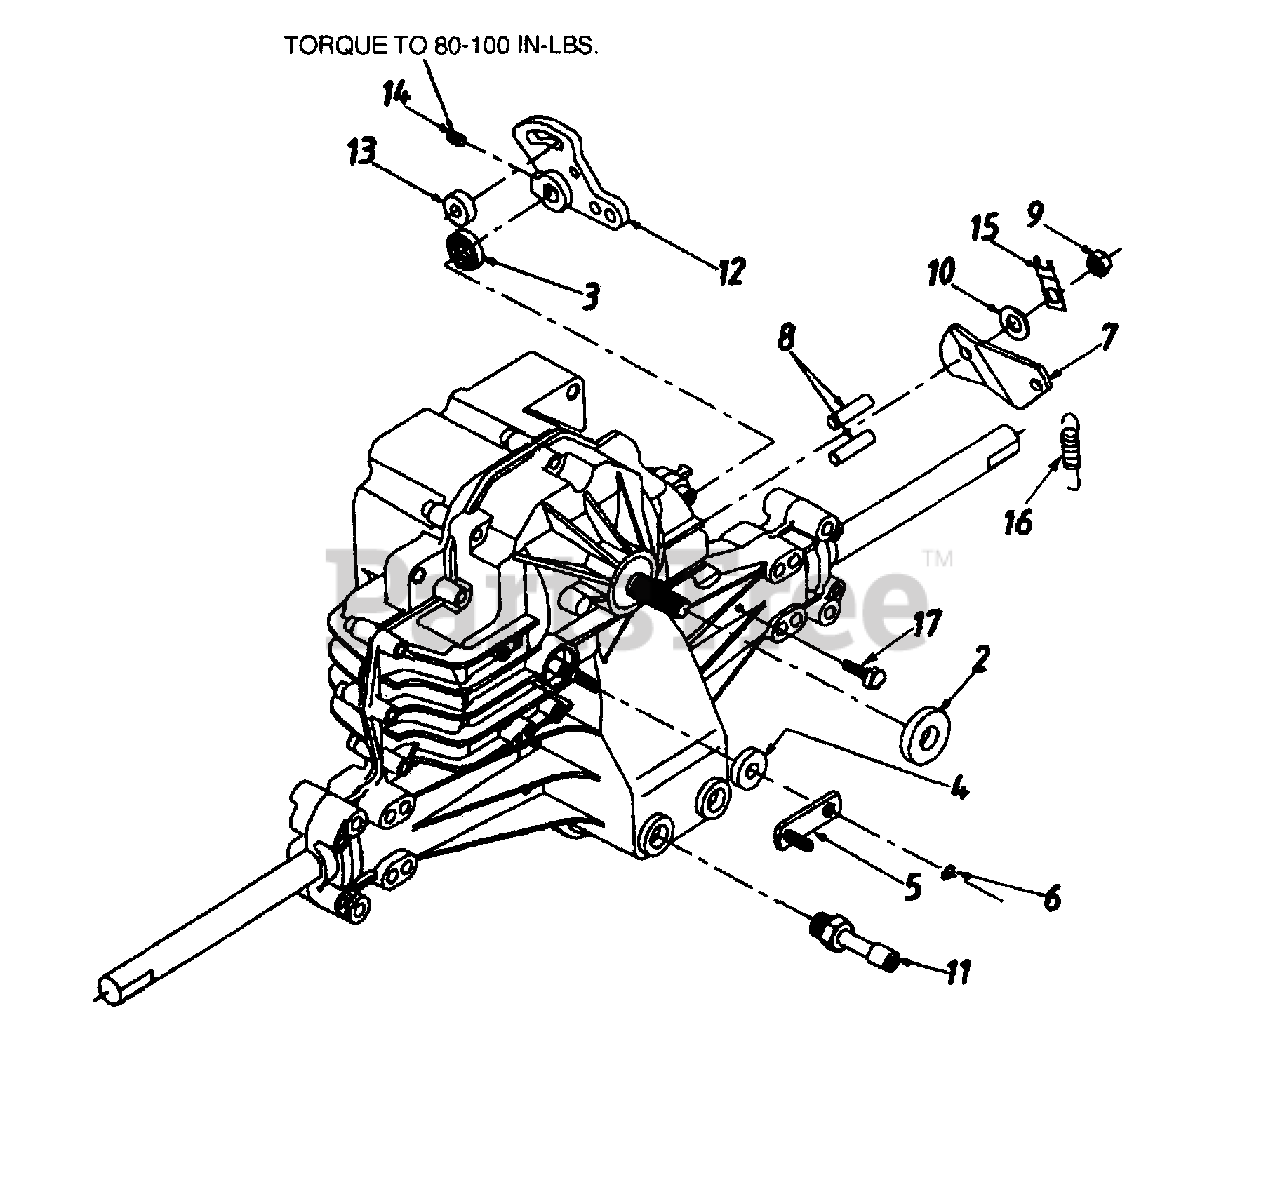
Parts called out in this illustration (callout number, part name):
4	Seal-Lip 10X25X7
5	Arm-Bypass
6	Ring-Retaining
7	Arm-Actuating
8	Pin-Actuating
9	Nut-Hex Lock 5/16-24
10	Washer 7/16" x 7/8" x .06"
11	Breather Ass'y.
12	Arm-Control
13	Puck-Dampener
14	Set Screw
15	Strap, Locking
16	Ext. Spring
17	Self Tapping Scr. #10-32
